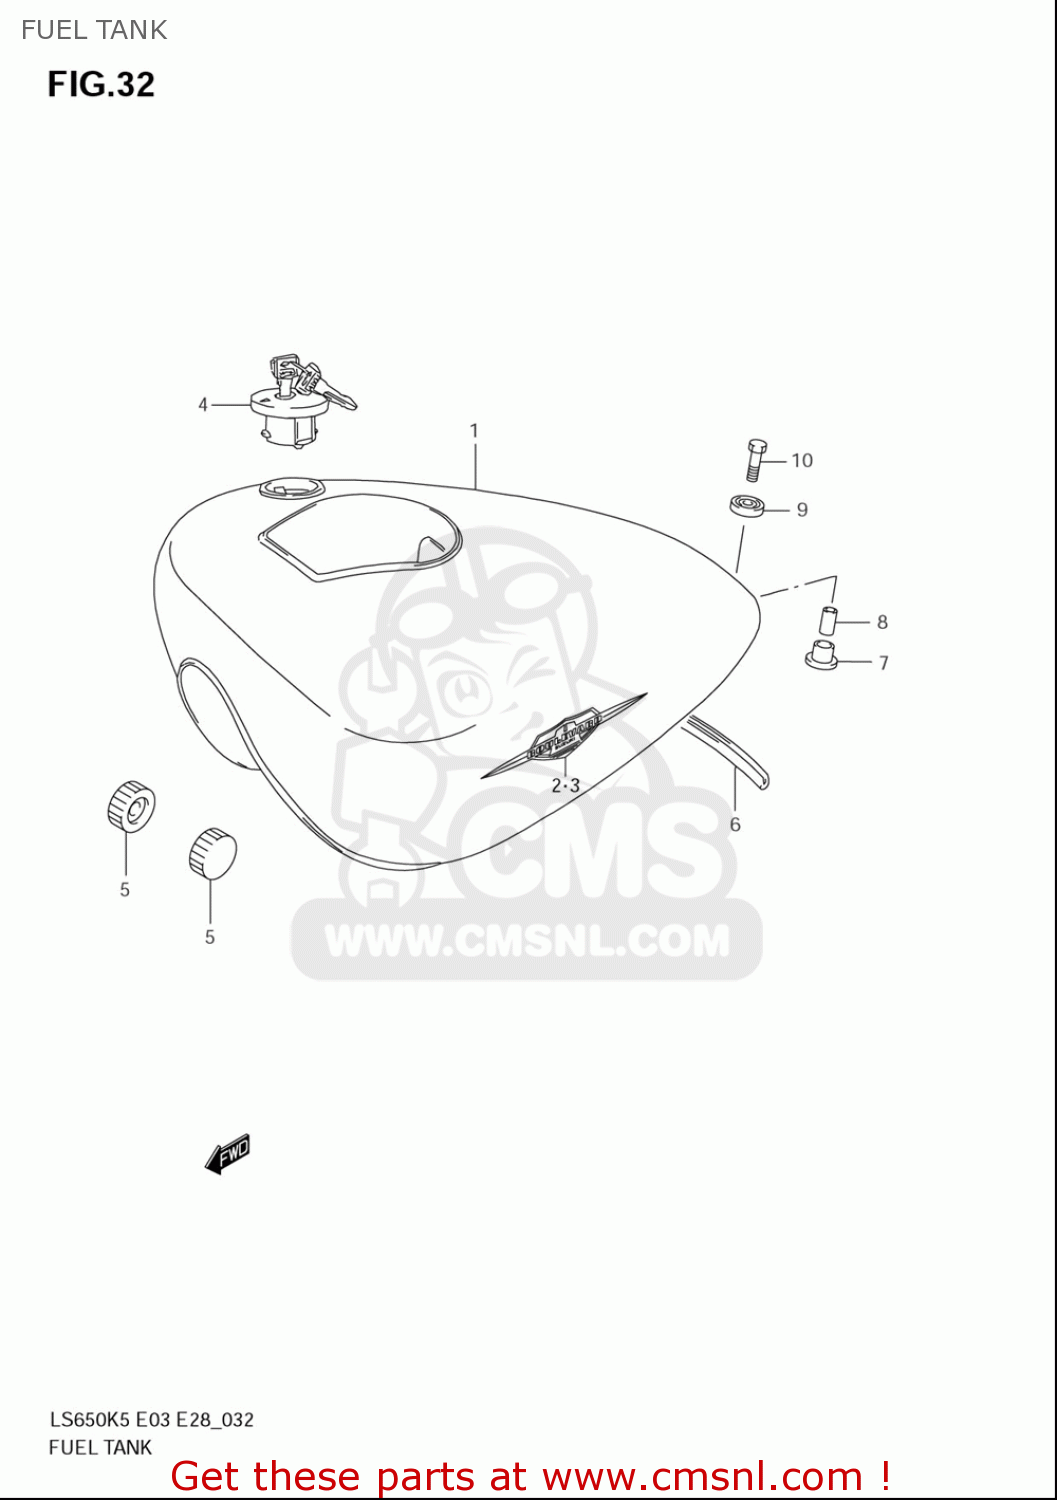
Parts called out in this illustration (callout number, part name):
1	TANK ASSY, FUEL (BLACK)
2	EMBLEM, RH
3	EMBLEM, LH
4	CAP SET,FUEL TANK
5	CUSHION
6	MOLDING,FUEL TANK RR
7	CUSHION
8	SPACER(6.5X9X18)
9	CUSHION
10	BOLT
